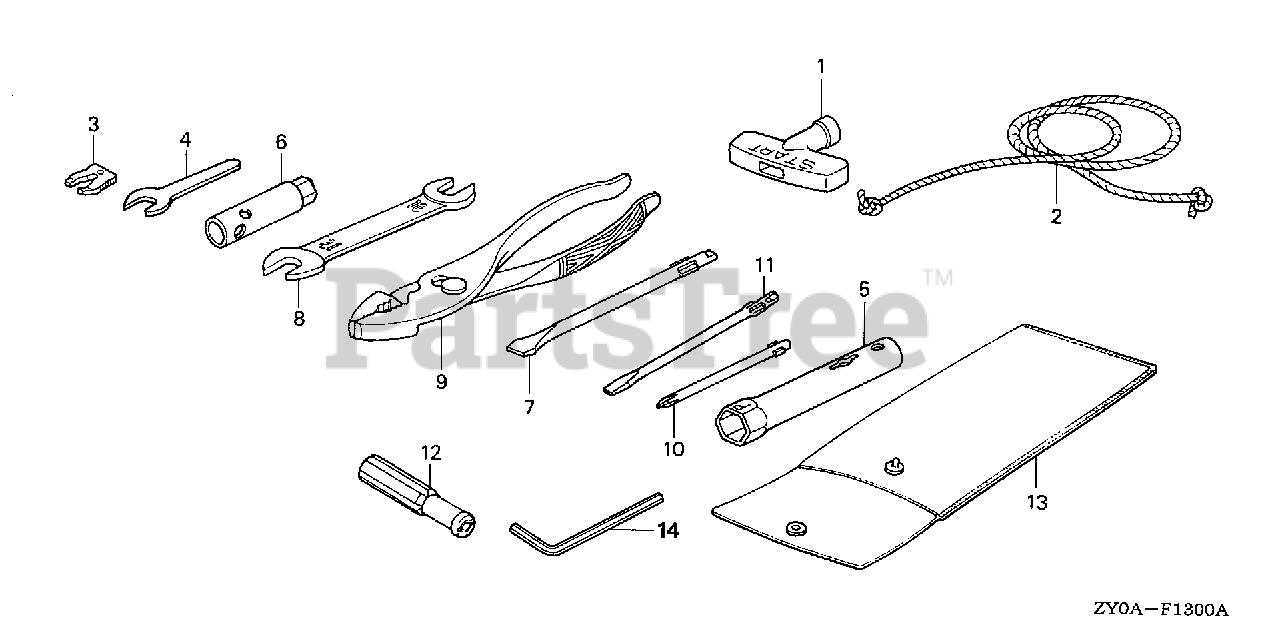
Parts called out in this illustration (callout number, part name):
1	GRIP, STARTER
1	KNOB, RECOIL SRARTER
2	ROPE, RECOIL STARTER (1300MM)
3	CLIP, EMERGENCY LOCK
4	SPANNER (8MM) (NOT AVAILABLE)
5	WRENCH, SPARK PLUG
6	WRENCH, BOX (10MM)
7	SCREWDRIVER, CHECK BOLT
8	SPANNER (10X12)
9	PLIERS (135) (KOWA)
9	PLIERS (135)
10	DRIVER 1, PLUS SCREW (NO.2)
11	DRIVER 3, MINUS SCREW (NO.2)
12	GRIP, SCREW DRIVER
13	BAG, TOOL (160MM)
14	WRENCH, HEX. (4MM)
